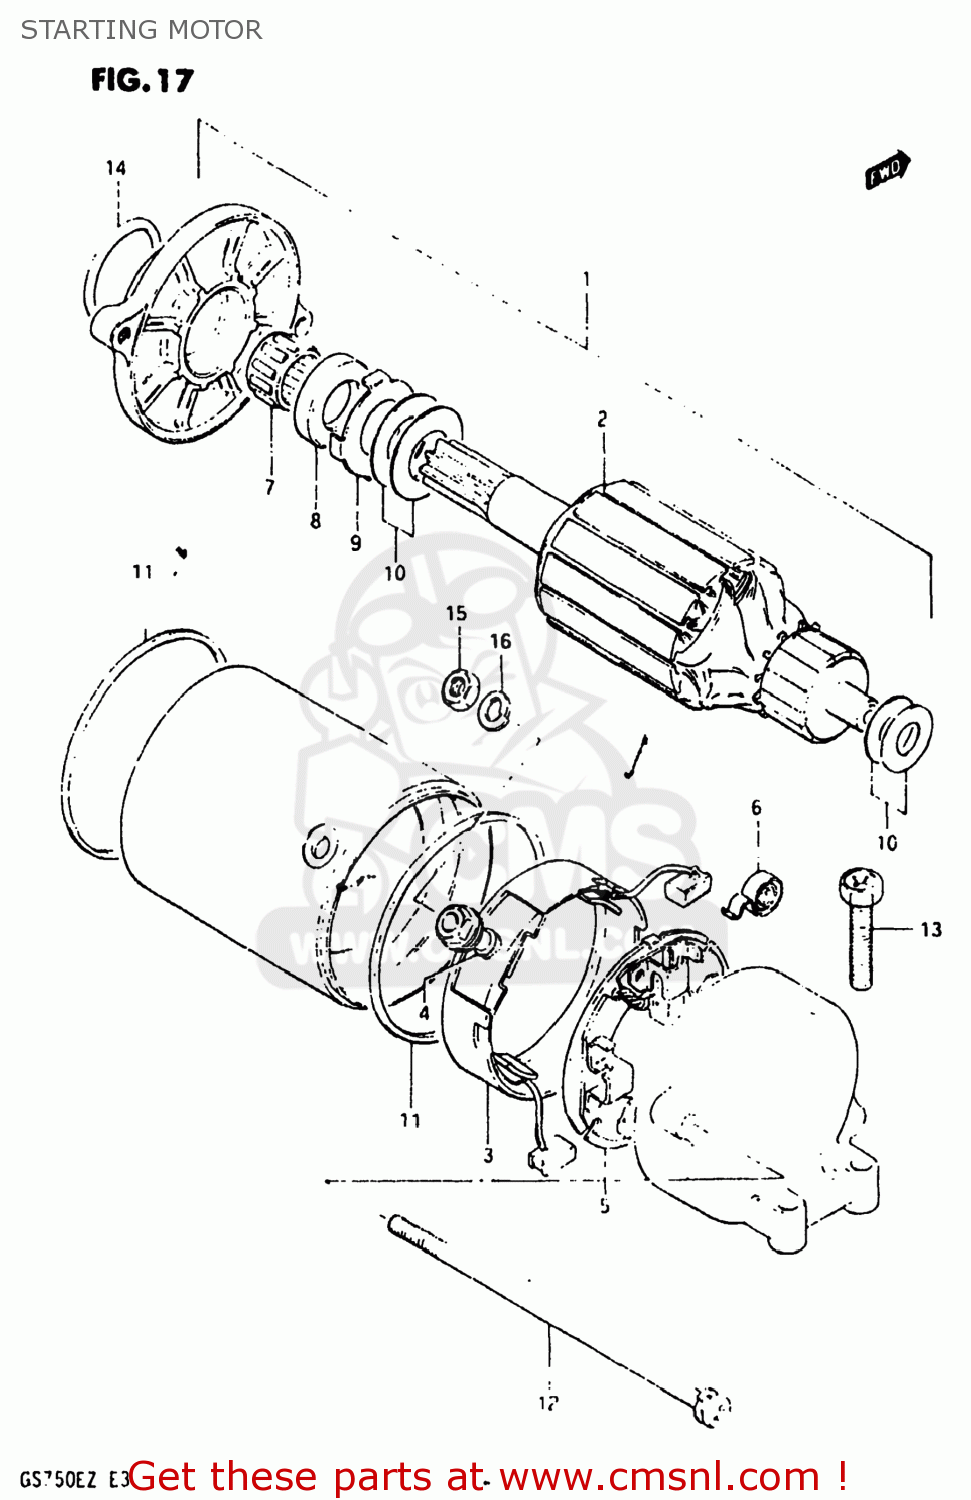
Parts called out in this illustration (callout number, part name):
1	MOTOR ASSEMBLY,STARTING
2	ARMATURE
3	BRUSH TERMINAL SET (+)
4	O RING
5	HOLDER,BRUSH
6	SPRING,BRUSH
7	BEARING
8	SEAL,OIL
9	SHIM SET
10	SHIM SET
11	SEAL,RING
12	BOLT,STARTING MOTOR HOUSING
13	SCREW (6X25)
14	O RING(D:2,ID:24.5)
15	NUT 6MM
16	LOCK WASHER
